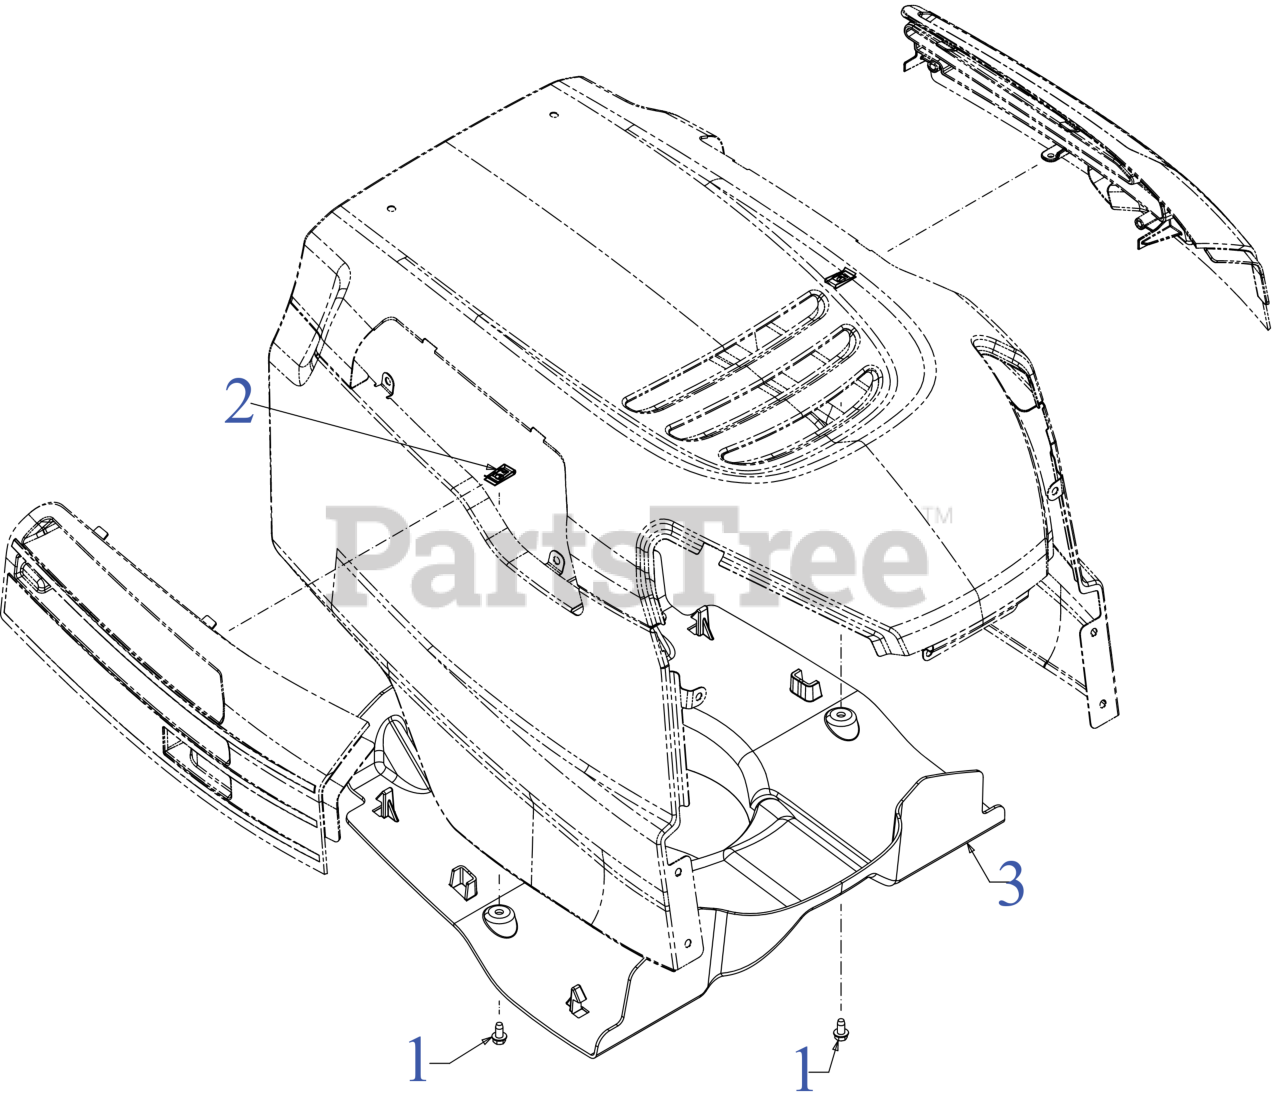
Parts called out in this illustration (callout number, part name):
1	SCREW 1/4-20 X.500
2	SPEED NUT
3	HOOD PLENUM
